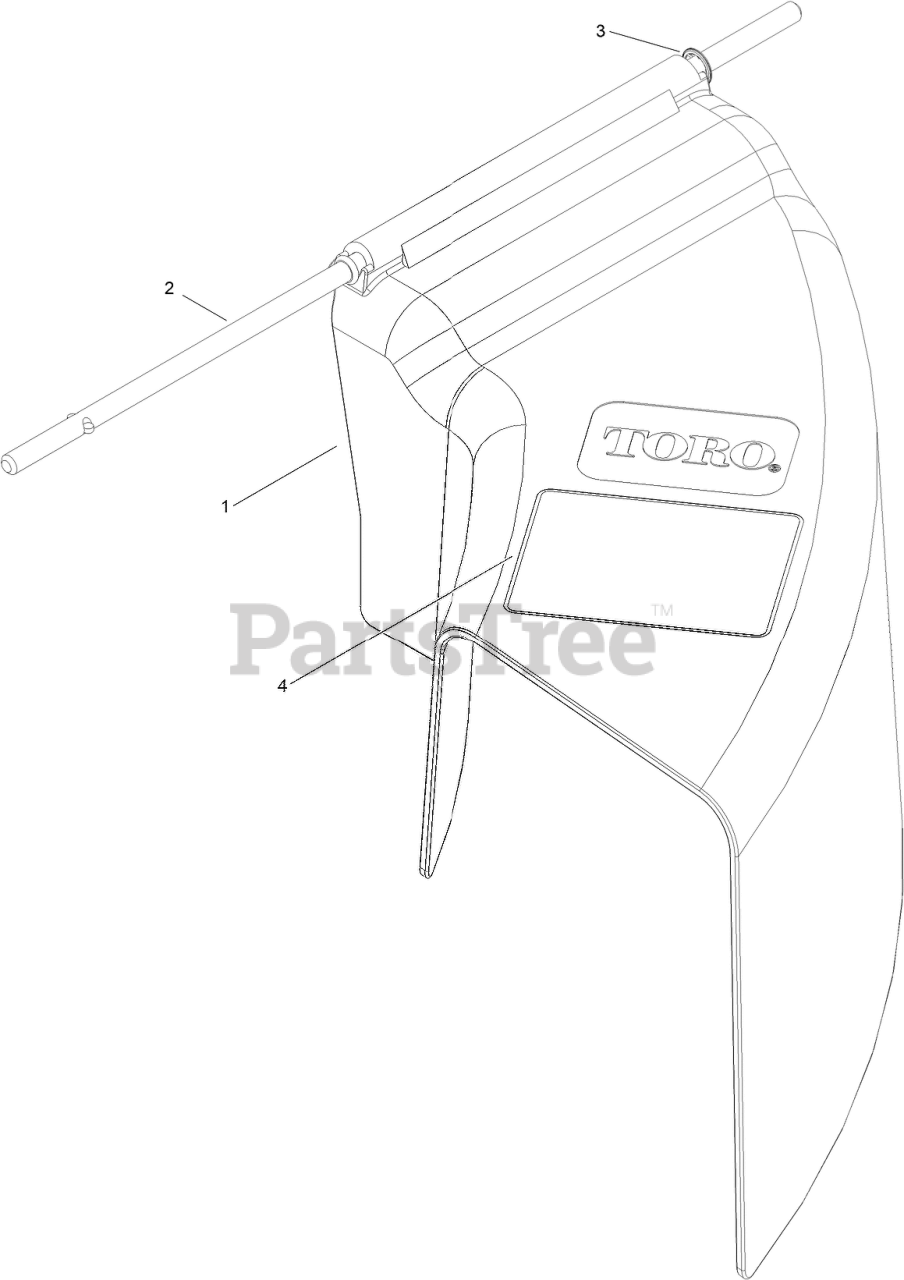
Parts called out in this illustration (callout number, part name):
1	CHUTE-DISCHARGE, SIDE
2	ROD-DISCHARGE
3	RING-RETAINING
4	DECAL-WARNING
